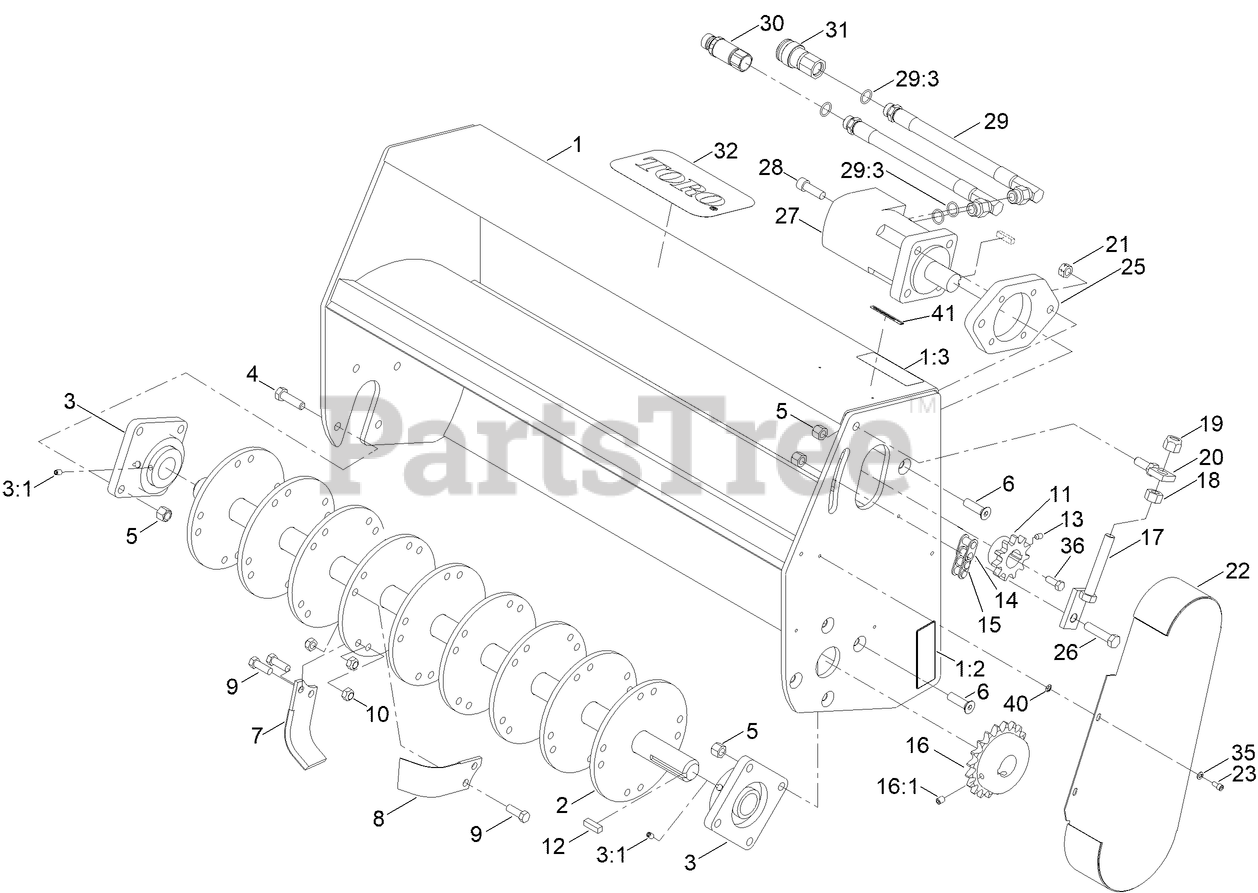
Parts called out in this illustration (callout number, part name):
1	TILLER FRAME ASM
1:2	DECAL-DANGER
1:3	DECAL-WARNING
2	SHAFT-TINE
3	BEARING ASM
3:1	SETSCREW-HSH
4	SCREW-HH
5	NUT-LOCK, NI
7	TINE-RH
8	TINE-LH
9	SCREW-HH
10	NUT-HEX
11	SPROCKET-11 TOOTH
12	KEY-SQUARE
13	SCREW-SET
14	CHAIN-ROLLER
15	LINK-CONNECTING
16	SPROCKET-20 TOOTH
16:1	SCREW-HSH
17	CHAIN ADJUSTMENT ASM
18	NUT-HEX
19	NUT-LOCK, NI
20	HOLDER-ADJUSTMENT
21	NUT-SIDE DEFORM
22	COVER-CHAIN, TILLER
23	SCREW-HSH
25	PLATE-MOUNT, MOTOR
26	SCREW-HH
27	MOTOR-HYD
28	SCREW-HSH
29	HYD HOSE ASM
29:3	O-RING
30	NIPPLE-CONNECT, PRESSURE
31	COUPLER-FACE, FLUSH
32	DECAL
35	WASHER-LOCK
36	SCREW-HH
40	NUT-RETAINING
41	DECAL-WARNING
